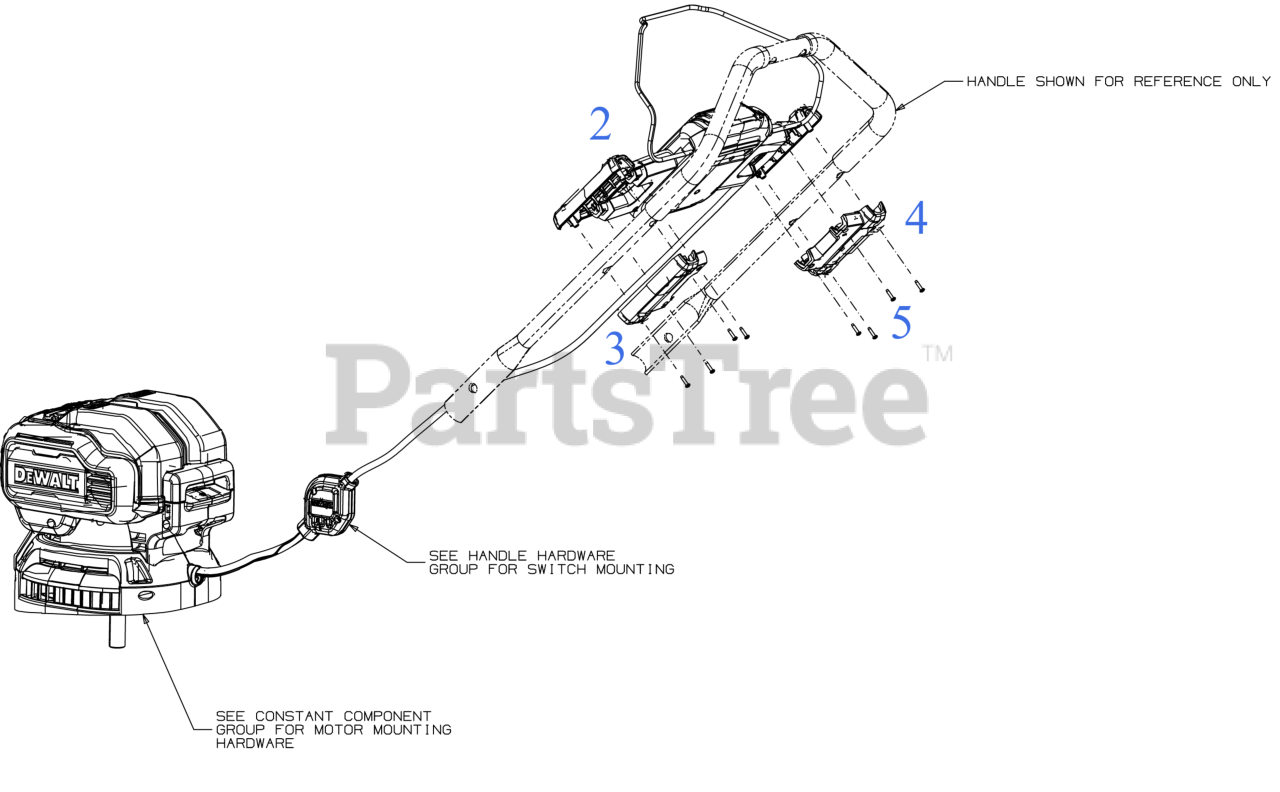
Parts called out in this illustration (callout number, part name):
2	MTR ASM:RWD:HNDL PNL
3	HANDLE PANEL COVER (REAR) (LH) (YELLOW)
4	HANDLE PANEL COVER (REAR) (RH) (YELLOW)
5	SCREW-TAP PLASTIC #6-19 X 0.62
